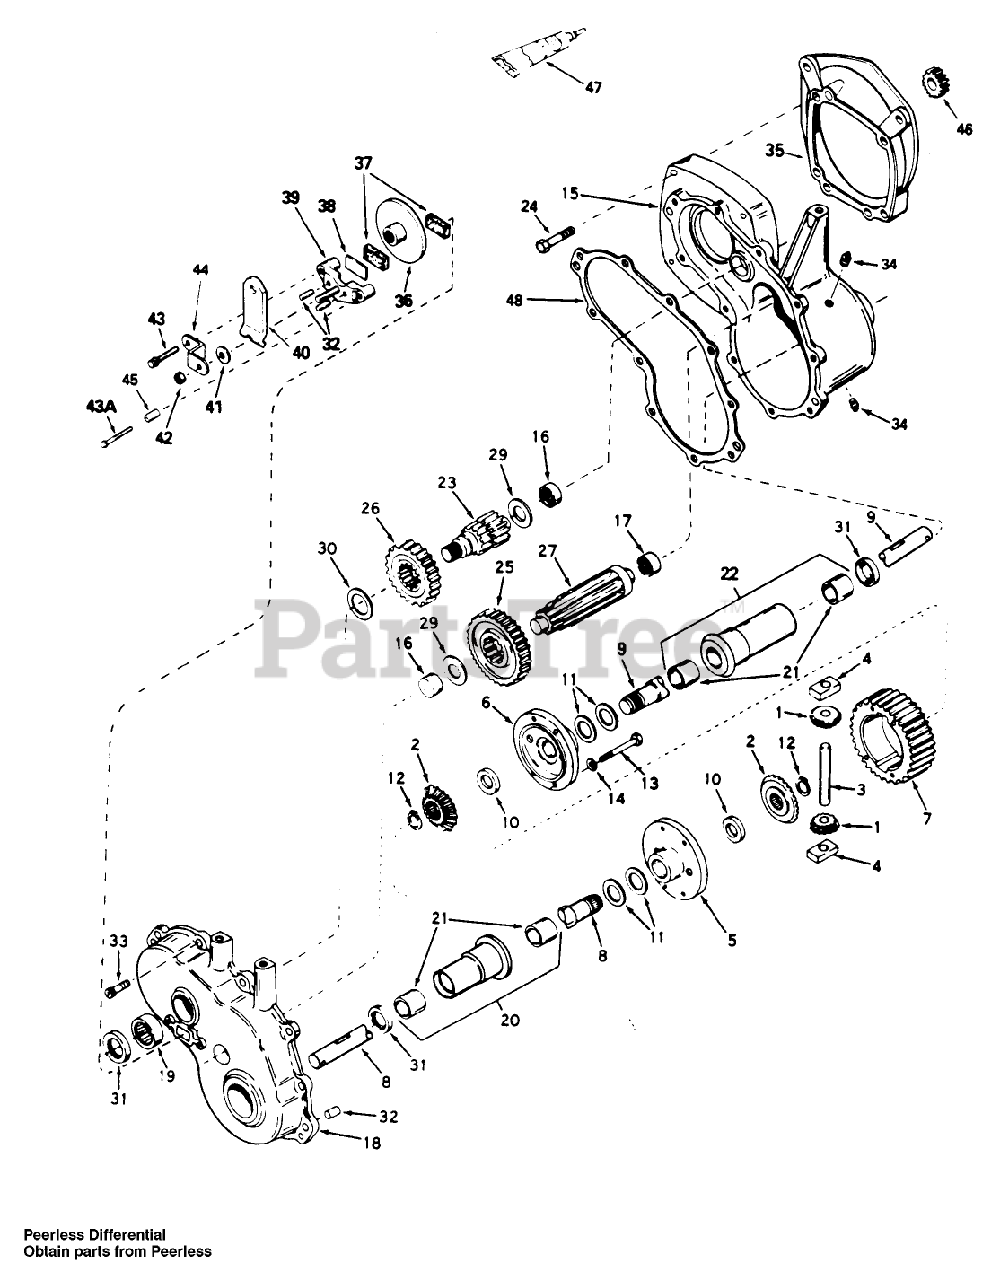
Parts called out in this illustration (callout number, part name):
1	Pinion-Bevel
2	Gear-Bevel
3	Pin-Drive
4	Biock-Drive
5	Carrier-Differential
6	Carrier-Differential
7	Gear-Ring
8	Axle-16-5/8"
9	Axle-21-57/64"
10	Washer
11	Washer
12	Ring-Snap
13	Screw-Hex Hd.
14	Lockwasher
15	Case Assembly (Incl. Ref. #16 & 17)
16	Bearing
17	Bearing-Needle
18	Cover Assembly (Incl. Ref. #16 & 19)
19	Bearing Needle
20	Housing Assembly-6-5/8" (Incl. Ref. #21)
21	Bushing
22	Housing Assembly-8-5/8" (Incl. Ref. #21)
23	Shaft-Brake
24	Screw-Hex Hd.
25	Gear-Output
26	Gear-Spur
27	Shaft-Output
29	Washer
30	Washer
31	Seal-Oil
32	Dowel Pin
33	Screw-Thread Forming
34	Plug-Pipe
35	Plate-Adapter
36	Disc-Brake
37	Pad-Brake (Pack of 2)
38	Brake Pad Plate
39	Nozzle-Carburetor
40	Lever-Brake
41	Washer
42	Locknut
43	Screw
43A	Screw-Thread Forming
44	Bracket
45	Spacer
46	Gear-Spur 22T
47	Gasket Eliminator
48	Gasket
